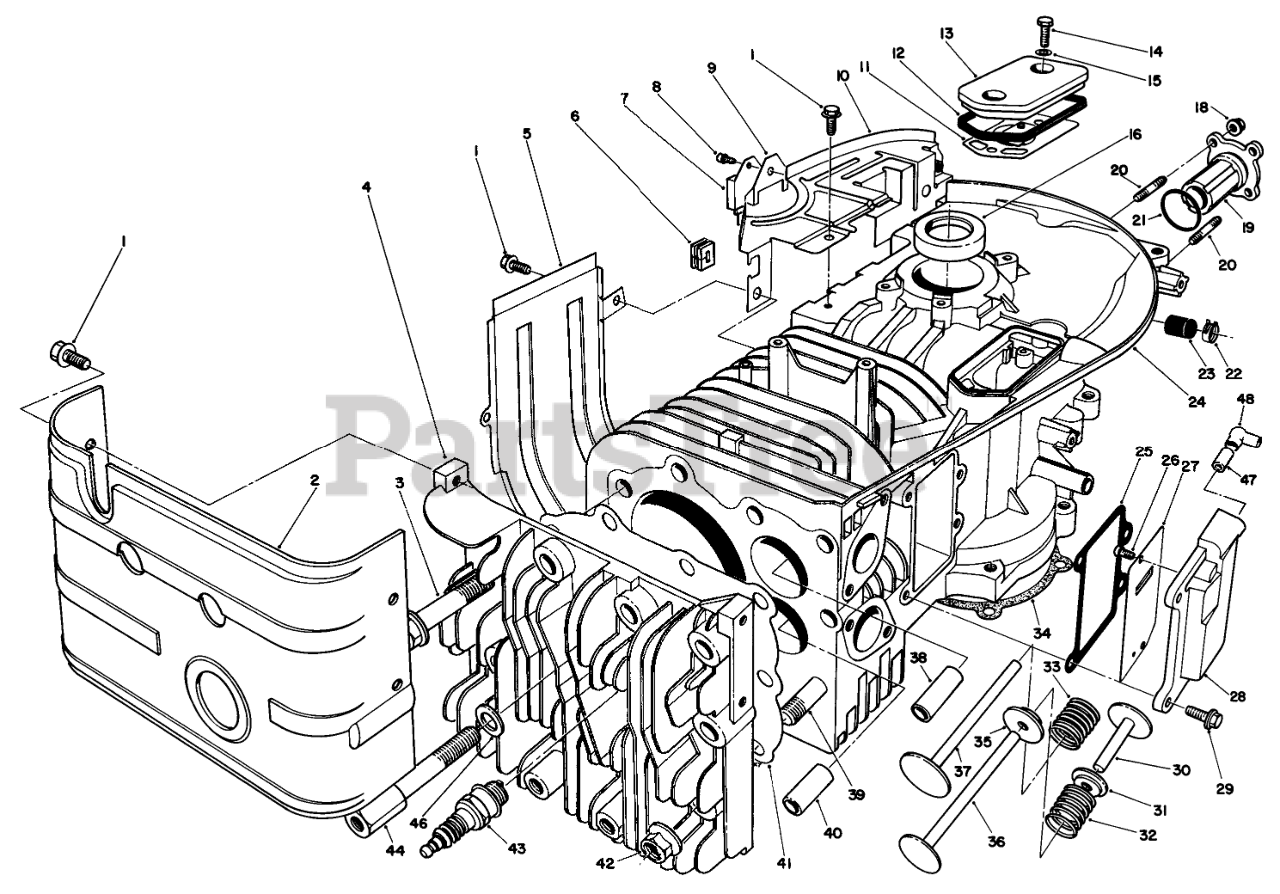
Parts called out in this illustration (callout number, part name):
1	Bolt-Flanged (6X10)
4	Cylinder Head
6	Grommet
7	Igniter
10	Fan Housing
11	Breather
16	Oil Seal
24	Crankcase Assembly
28	Cover-Valve Chamber
29	Bolt-Flanged (6X16)
31	Retainer-Spring
32	Spring-Valve
33	Spring-Valve
35	Rotator
36	Exhaust Valve
37	Intake Valve
38	Guide-Intake Valve
40	Guide-Exhaust Valve
43	Spark Plug
46	Washer
